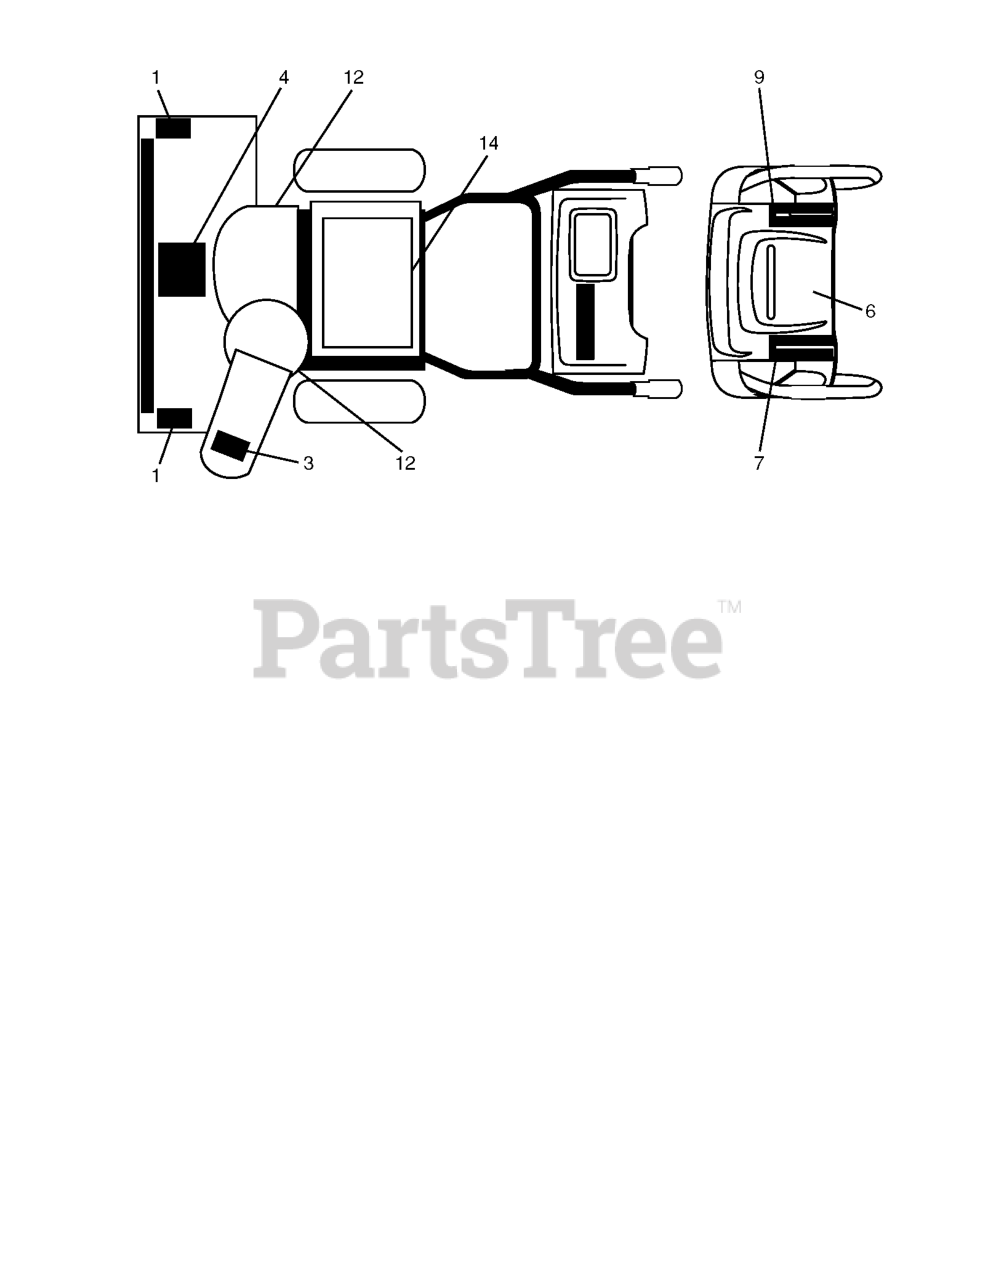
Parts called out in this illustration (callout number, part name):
1	DECAL.AUGER.SAFETY.
3	DECAL.CHUTE.SAFETY.
4	DECAL.AUGER."
7	DECAL.CONS.LT.SPD/LEV/PWRST.
9	DECAL.CONS.RT.SPD/LEV/PWRST.
12	DECAL.BELT.GUARD.
14	DECAL.FENDER
